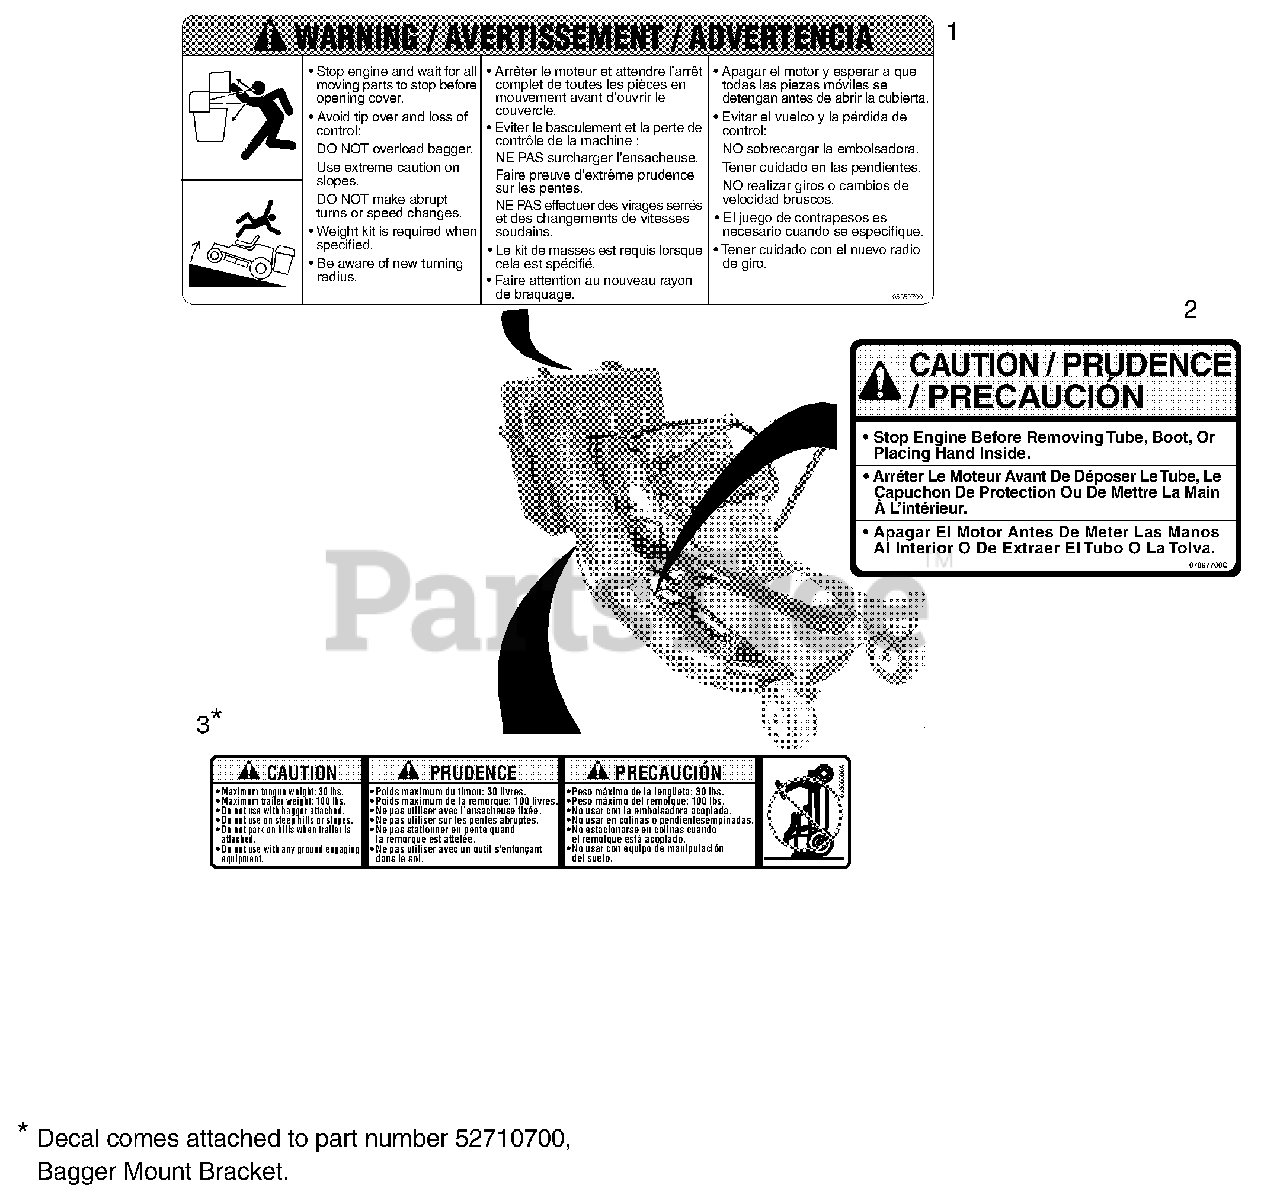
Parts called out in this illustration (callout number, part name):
1	Decal, Bagger Cover Warning
2	Decal, Boot Caution
3	Decal-Hitch 100#
